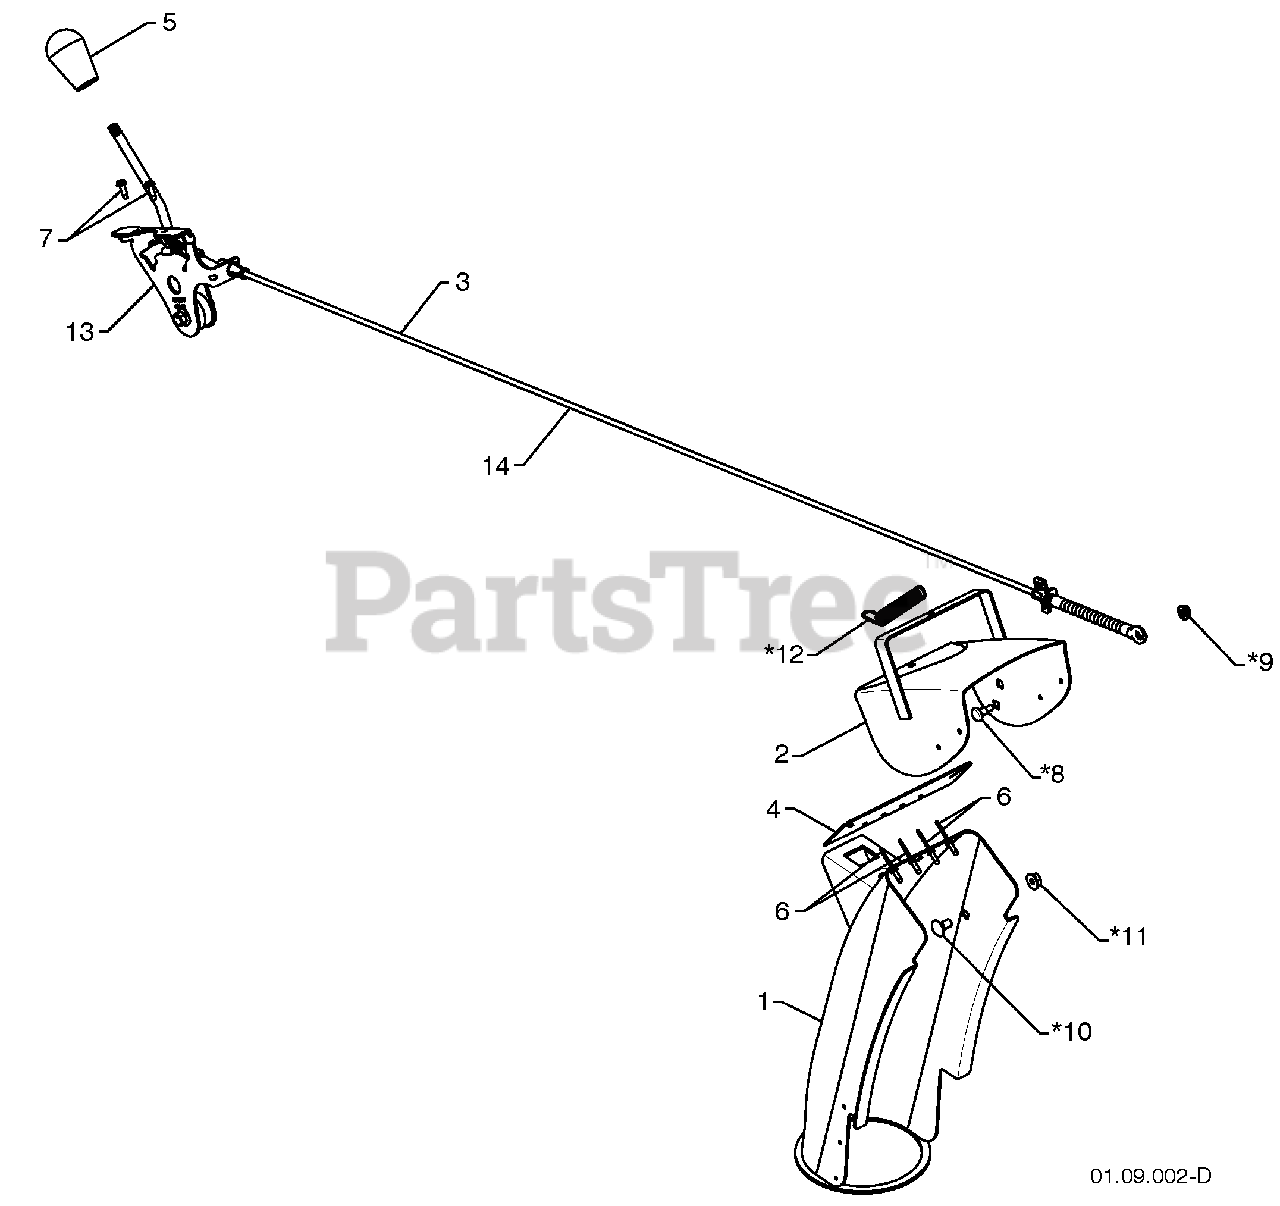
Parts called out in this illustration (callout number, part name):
1	CHUTE WELDMENT
2	DEFLECTOR WELDMENT
3	DEFLECTOR CONTROL ASSEMBLY
4	DEFLECTOR SEAL
5	KNOB BLACK
6	POP RIVET
7	SCREW 10-24 X .625
8	SHOULDER SCREW
9	NUT 1/4-20
10	CARRIAGE BOLT 5/16-18 X .50
11	NUT 5/16-18
12	DEFLECTOR SPRING
13	DEFLECTOR CONTROL HEAD
14	DEFLECTOR CONTROL CABLE
